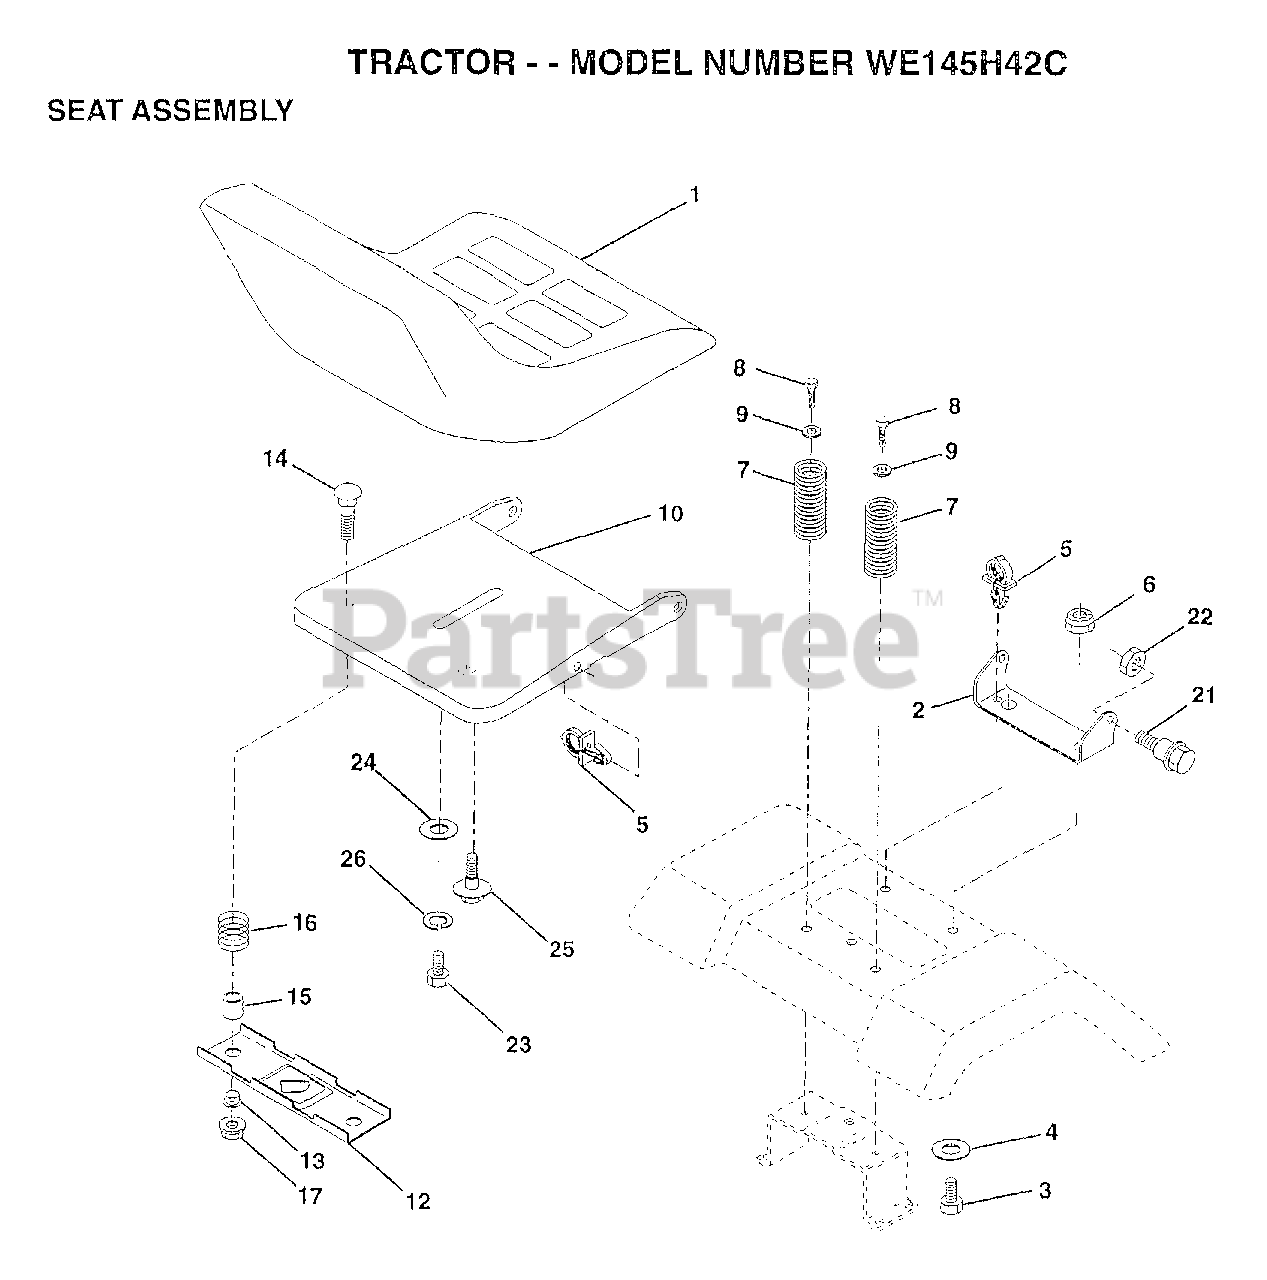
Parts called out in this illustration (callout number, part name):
2	BRACKET PVT SEAT
3	BOLT
4	WASHER PM
5	CLIP.PUSH-IN.HING
6	NUT
7	SPRING COMPRESSIO
8	SCREW GTV
9	WASHER
10	PAN-SEAT
12	BRKT SWITCH
13	BUSHING
14	BOLT-RD HD SQ NK
15	SPLIT SPACER
16	SPRING
21	"BOLT,SHOULDER"
22	NUT
23	BOLT
24	WASHER
25	"BOLT,SHOULDER"
26	LOCKWASHER
